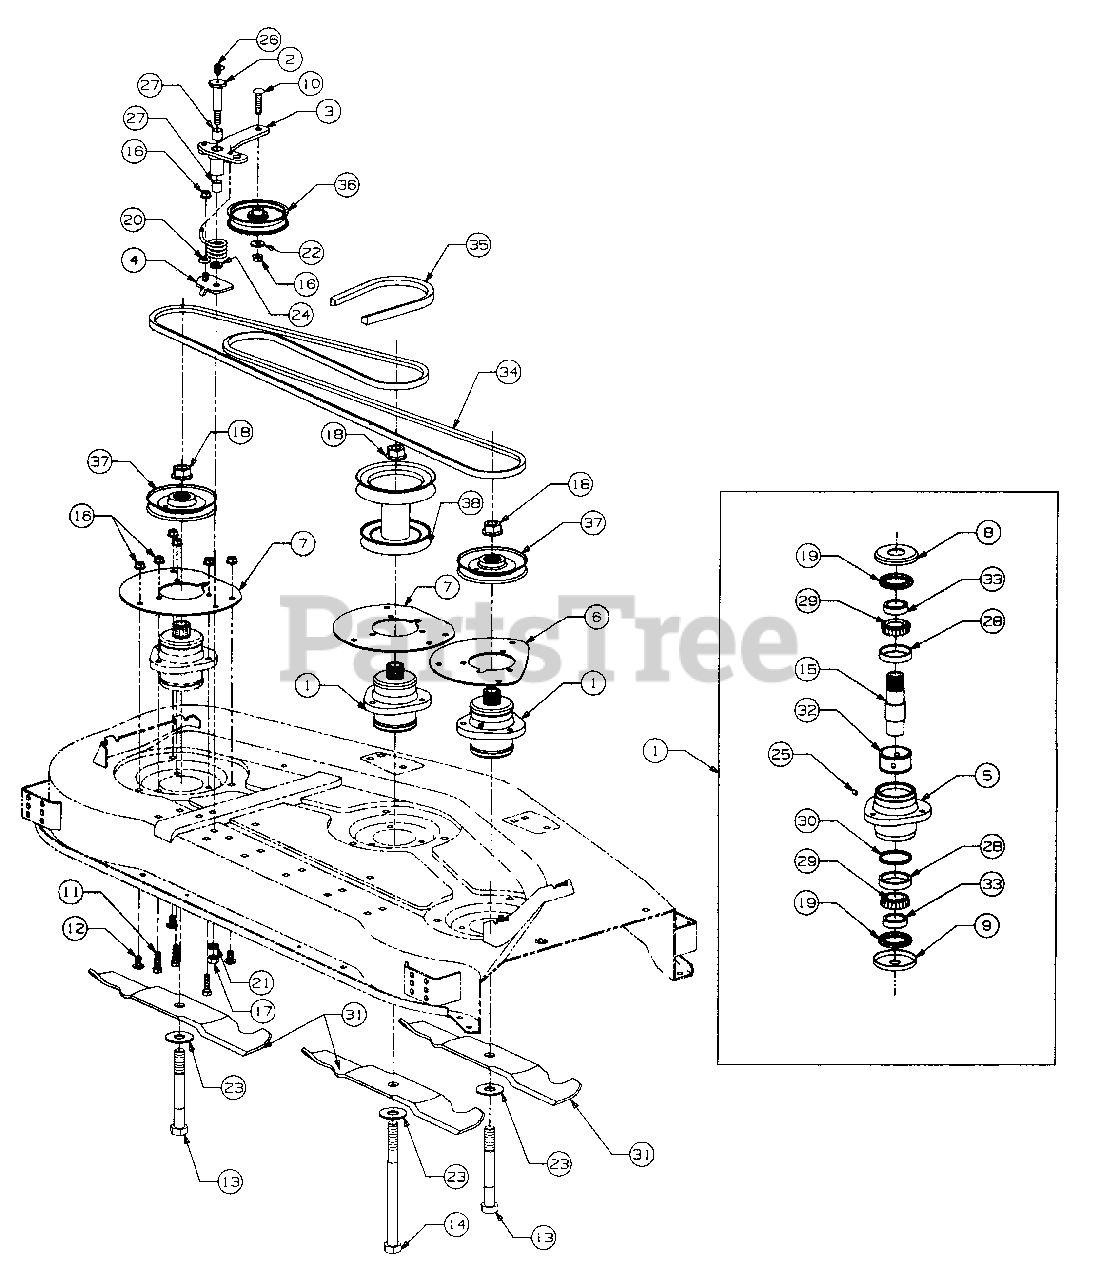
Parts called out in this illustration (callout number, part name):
1	Spindle Assy, complete
2	Bolt, Shoulder
5	Housing, Spindle
8	Cup, Top Spindle
10	Bolt, Carriage, 3/8-16 X 1.75 Lg
11	Screw, Hex Cap, 3/8-16 X 1.25 Lg GR5
12	Bolt, Sht Nk Carriage, 3/8-16 X .75 Lg GR5
13	Bolt, Hex Hd Blade, 3/4-16 X 6.0 Lg
14	Bolt, Hex Hd Blade, 3/4-16 X 9.50 Lg
15	Shaft, Blade Spindle
16	Nut, Hex Flanged Lock, 3/8-16
17	Nut, Hex, 7/16-14 GR5
18	Nut, Hex Flange, 3/4-16
19	Seal, Oil
20	Spring, Torsion
21	Washer, Lock, 7/16
22	Washer, Spec, .378 X 1.0 X .125 Thk
23	Washer, Flat, .781 X 2.0 X .105 Thk
24	Washer, Flat, .469 X .875 X .105 Thk
25	Fitting, Lube
26	Fitting, Lube, 90 Degree 1/4-28 Tapper Thd
27	Bearing, Sleeve
28	Cup, Bearing
29	Cone, Bearing
30	Spacer, Bearing
33	Ring, Seal
34	Belt, Spindle, A-Sect X 122.0 Lg
35	Belt, PTO, B-Sect X 62.04 Lg
36	Pulley, Flat Idler
37	V-Pulley, 4.65 OD
38	Pulley, Deck, 5.07 OD & 5.75 OD
